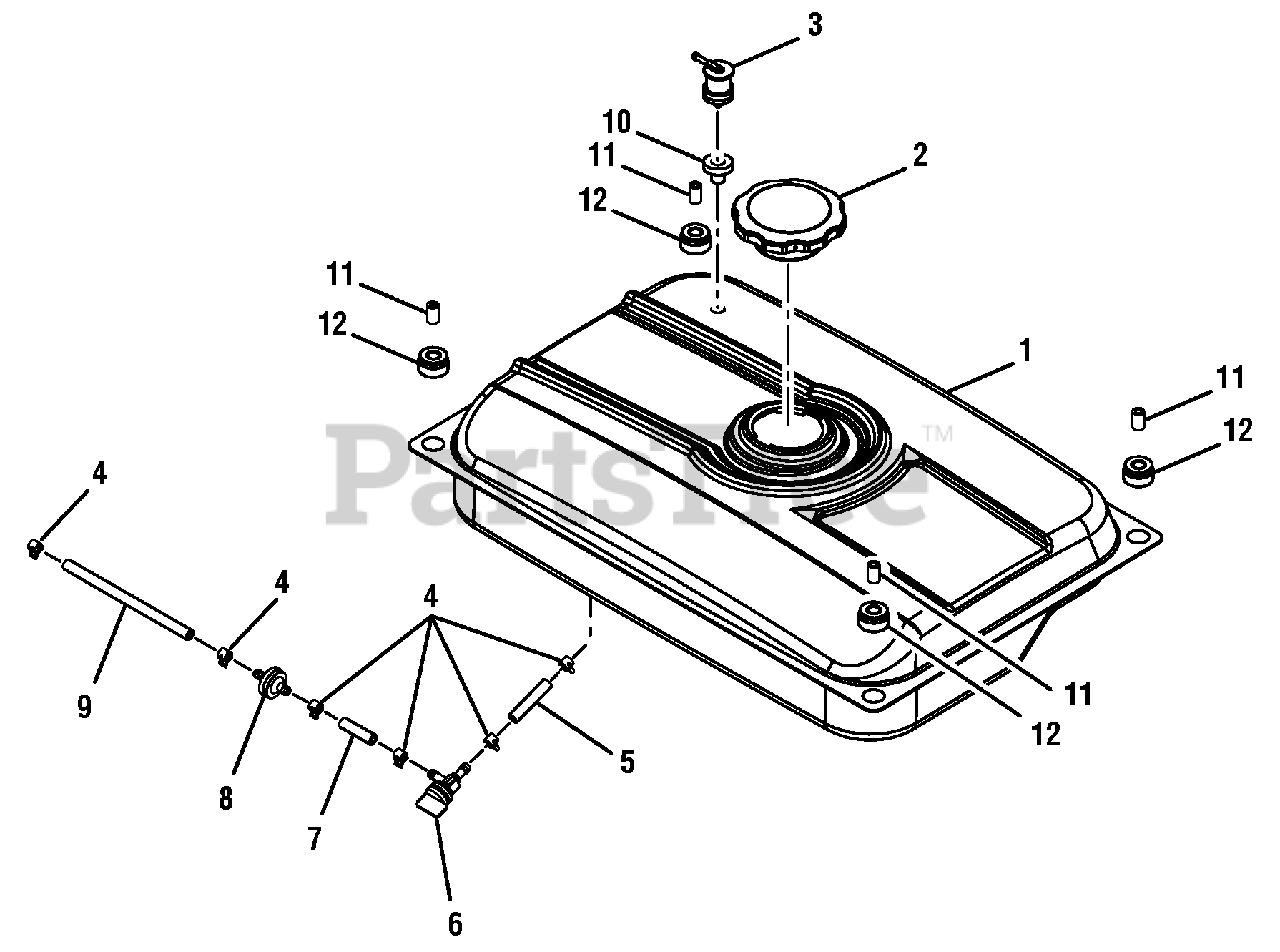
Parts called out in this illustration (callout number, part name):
1	Fuel Tank
3	Rollover Valve
5	Fuel Hose (45 mm)
6	Fuel Shut Off Valve
7	Fuel Hose (35 mm)
8	Fuel Filter
9	Fuel Line (144 mm)
